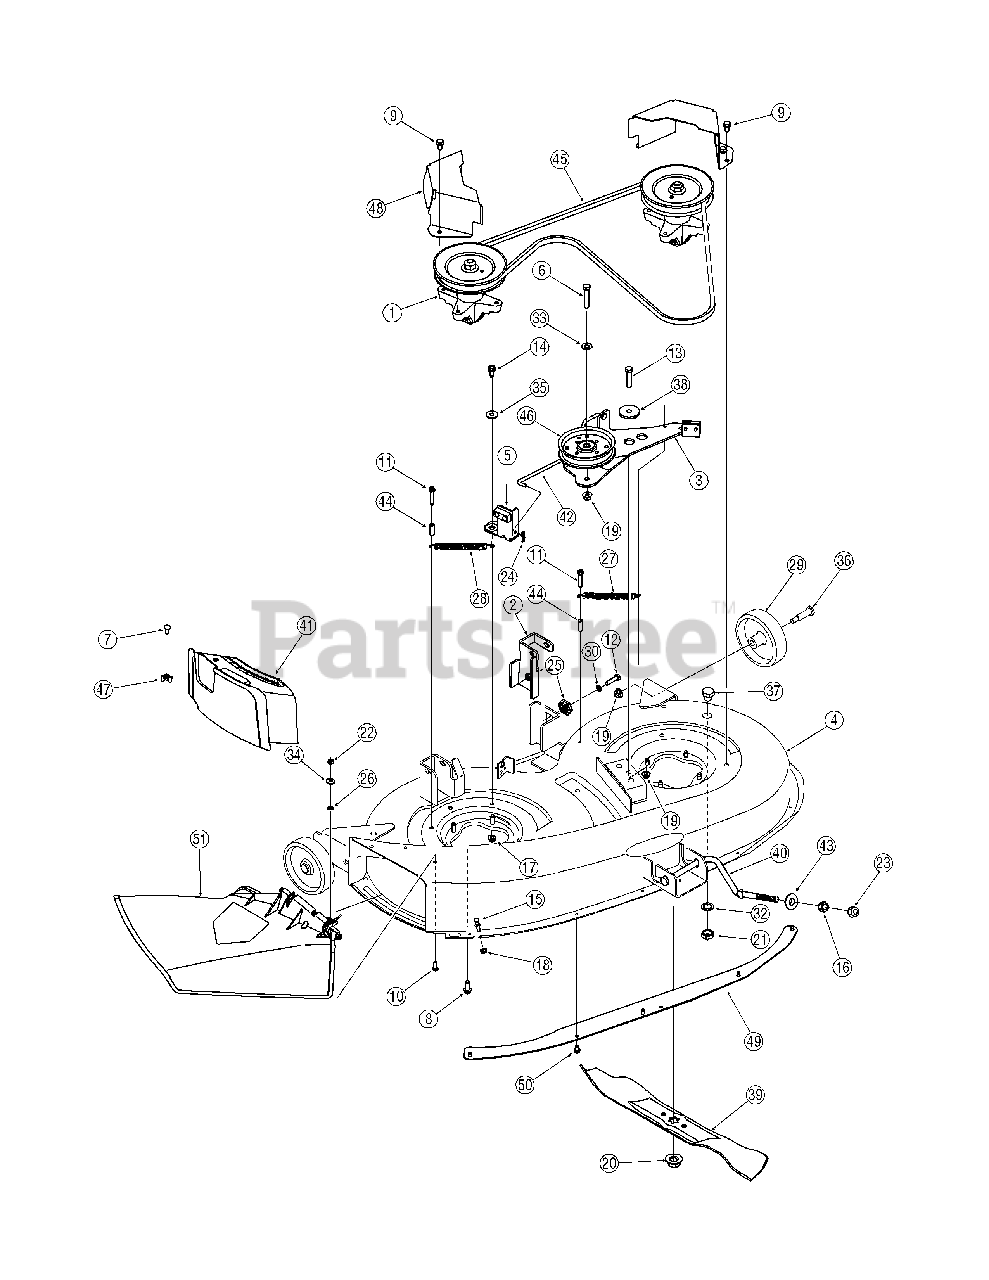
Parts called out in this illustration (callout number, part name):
1	Spindle Assembly, Pul, 5.75" Dia
6	Screw, 3/8-16, 1.75, Gr5
7	Carriage Screw, , 1/4-20 x .62
8	Screw, 5/16-18, 0.875
9	Screw, 5/16-12, 0.750
10	Screw, 1/4-20, .620, Gr5
11	Screw, 1/4-20, 1.500
12	Screw, 5/16-18, 1.250
13	Screw, 3/8-16, 1.25, Gr5
14	Screw, 5/16-18, .75, Gr5
15	Pin, Grasscatcher, 1/4-20
16	Nut, Hex, 1/2-13, Gr5
17	Nut, Flange Lock, 5/16-18, GrF, Nylon
18	Nut, Flange Lock, 1/4-20, GrF, Nylon
19	Nut, Flange Lock, 3/8-16, GrF, Nylon
20	Nut, Flange, 5/8-18
21	Nut, Hex, M16-1.5
22	Nut, Hex, 1/4-20, Gr5
23	Nut, Hex Lock, 1/2-13, Gr8, Nylon
24	Pin, Cot, .072 Dia. x 1.13 Lg
25	Gear, Deck Adjustment
26	Nut, Push, .25 ID x .50 OD
27	Spring, Extension, .50 Dia. x 6.37
28	Spring, Extension, .50 Dia. x 6.375
29	Wheel, Deck 5.0 x 1.38
30	Washer, Lock, 5/16
31	Washer, Flat, .64 x 1.24 x .06
32	Washer, Lock, 5/8, Internal Tooth
33	Washer, Flat, .385 x .87 x .06
34	Washer, Bell, .265 x.75 x .062
35	Bushing, Shoulder, .320 ID x .135
36	Screw, Shoulder, .498 x 1.53, 3/8-16
37	Plug, Screw, M16 x 1.5
38	Spacer, Shoulder, .8540 x .190
39	Blade, 19.38", Star 3-in-1
40	Deck Rod, Front Adjustable
41	Mulch Plug
42	Control Rod, Brake
43	Pivot Cup, Deck Lift
44	Spacer, .260 x .372 x 1.030
45	Belt, V-Type
46	Idler Pulley, 4.25" Dia.
47	Wing Nut, 1/4-20
50	Screw, 1/4-20, .500
51	Chute Assembly, Discharge
